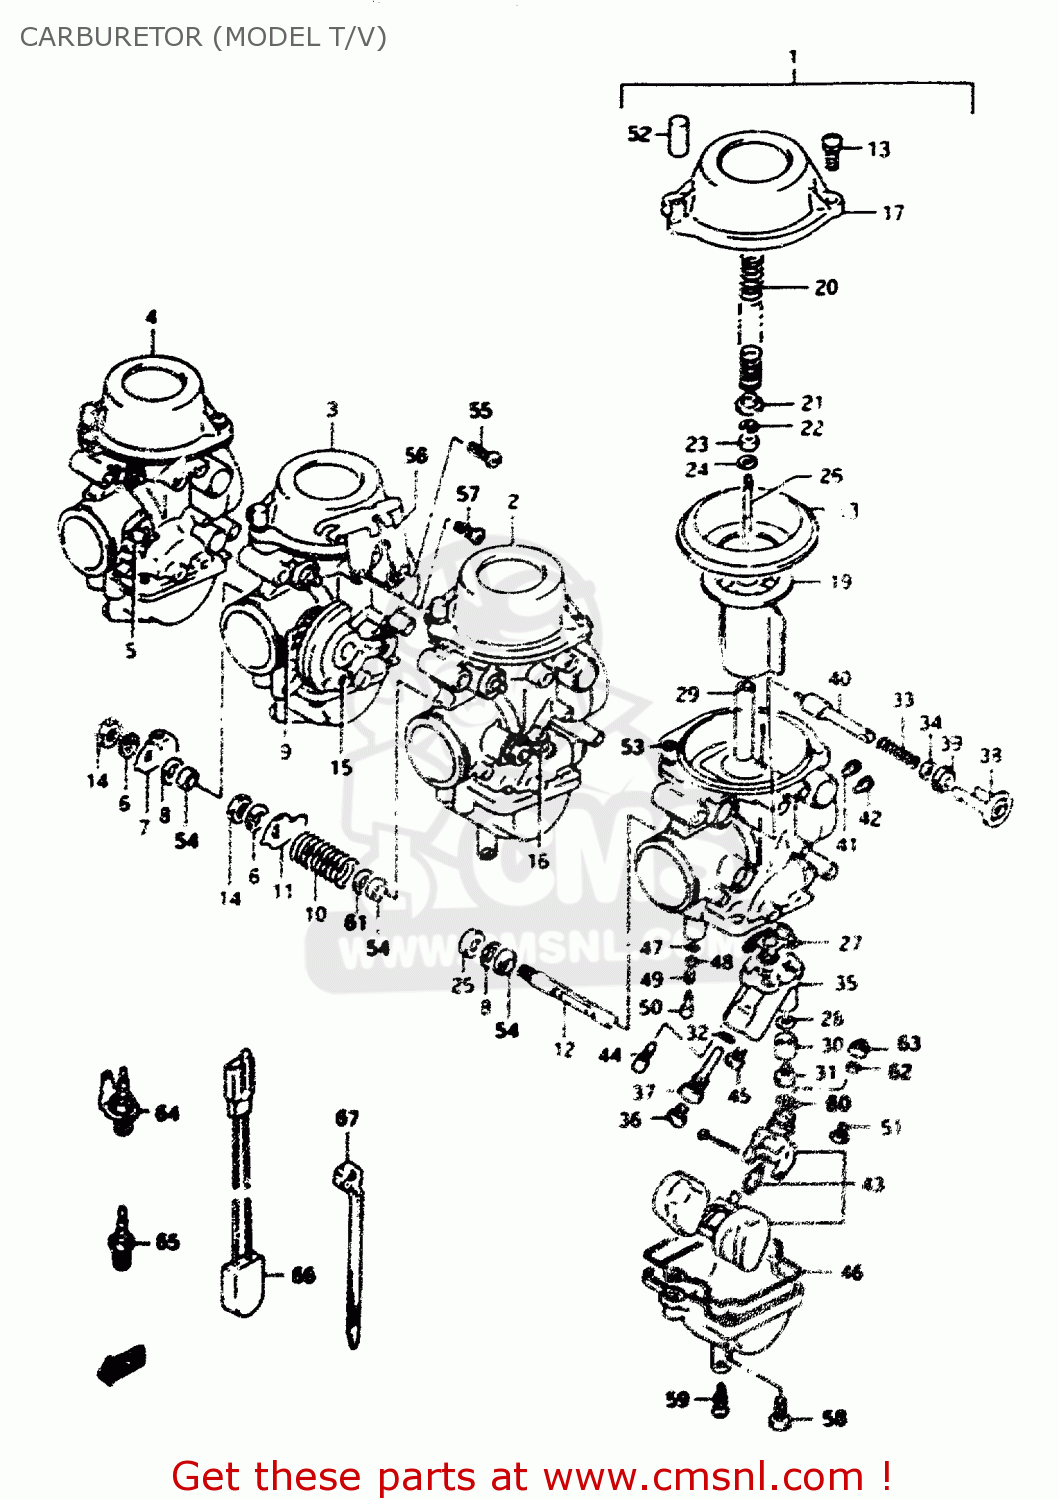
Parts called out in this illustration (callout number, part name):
1	CARBURETOR ASSY,LH
2	CARBURETOR ASSY,ML
3	CARBURETOR ASSY,MR
4	CARBURETOR ASSY,RH
5	SHAFT,THROTTLE
6	WASHER,LOCK
7	LEVER,THROTTLE
8	GASKET,THROTTLE SHAFT (NAS)
9	SPRING
10	SPRING
11	SHAFT,THROTTLE
12	SHAFT,THROTTLE
13	SCREW
14	NUT
15	SHAFT,THROTTLE
16	LEVER,THROTTLE
17	COVER,DIAPHRAGM
18	DIAPHRAGM
19	VALVE,PISTON
20	SPRING
21	RING
22	E RING
23	RING
24	WASHER
25	RING
26	NEEDLE,JET(5D44)
27	O RING
28	GASKET (NAS)
29	JET,NEEDLE(O-9)
30	RING
31	SCREW
32	O RING
33	SPRING
34	WASHER
35	JET BLOCK ASSEMBLY
36	JET,MAIN(120)
37	HOLDER,JET
38	HOLDER,GUIDE
39	CAP,STARTER
40	PLUNGER ASSY
41	JET,AIR(0.6)
42	JET,AIR
43	FLOAT/NEEDLE VALVE ASSY
44	JET,PILOT(12.5)
45	JET,STARTER(47.5)
46	SEAL
47	O RING,PILOT AIR SCREW
48	WASHER
49	SPRING
50	SCREW,PILOT
51	SCREW
52	CAP
53	O RING
54	SEAL
55	SCREW(5X14)
56	BRACKET
57	SCREW
58	SCREW
59	SCREW,DRAIN
60	O RING
61	RING
62	RING
63	FILTER
64	HEATER ASSEMBLY,CARBURETOR
65	HEATER,CARBURETOR (15W)
66	THERMO SWITCH,CARB HEATER
67	CLAMP(L:125)
